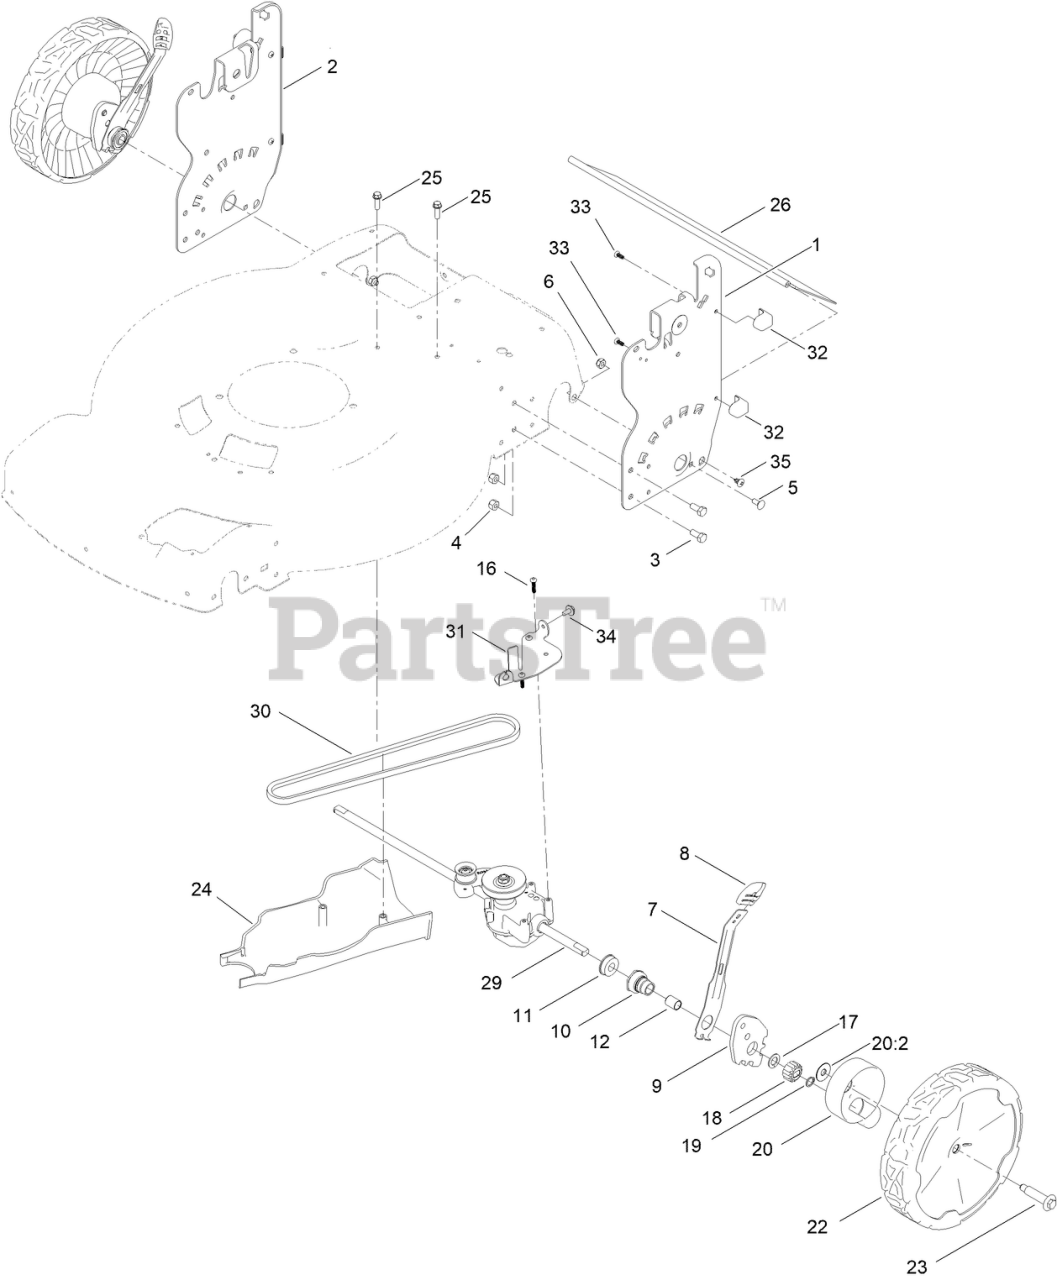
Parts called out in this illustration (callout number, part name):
1	PLATE-HOC, LH
2	PLATE-HOC, RH (2 HOLE)
3	SCREW-HH
4	NUT-HEX
5	BOLT-CARR
6	NUT-LOCK
7	ARM-SPRING
8	KNOB-HOC
9	ARM-PIVOT, REAR
10	RETAINER-BUSHING, HOC
11	BEARING-BALL
12	BUSHING-SLEEVE
16	SCREW-PLASTITE
17	WASHER-THRUST
18	GEAR-PINION, 15T
19	RING-RETAINING
20	ASM-COVER, GEAR (DK GRAY)
20:2	WASHER-STEPPED
22	ASM-9.65" WHEEL, GEARED
23	BOLT-SHOULDER
24	COVER-BELT, REAR
25	SCREW-PLASTITE, HWH
26	SHIELD-TRAILING
29	TRANSMISSION-AWD
30	BELT-AWD, 34.50
31	GUIDE-BELT, AWD
32	PAD-SMART STOW
33	SCREW-PPH
34	SCREW-HWH, THD ROLL
35	SCREW-THD
